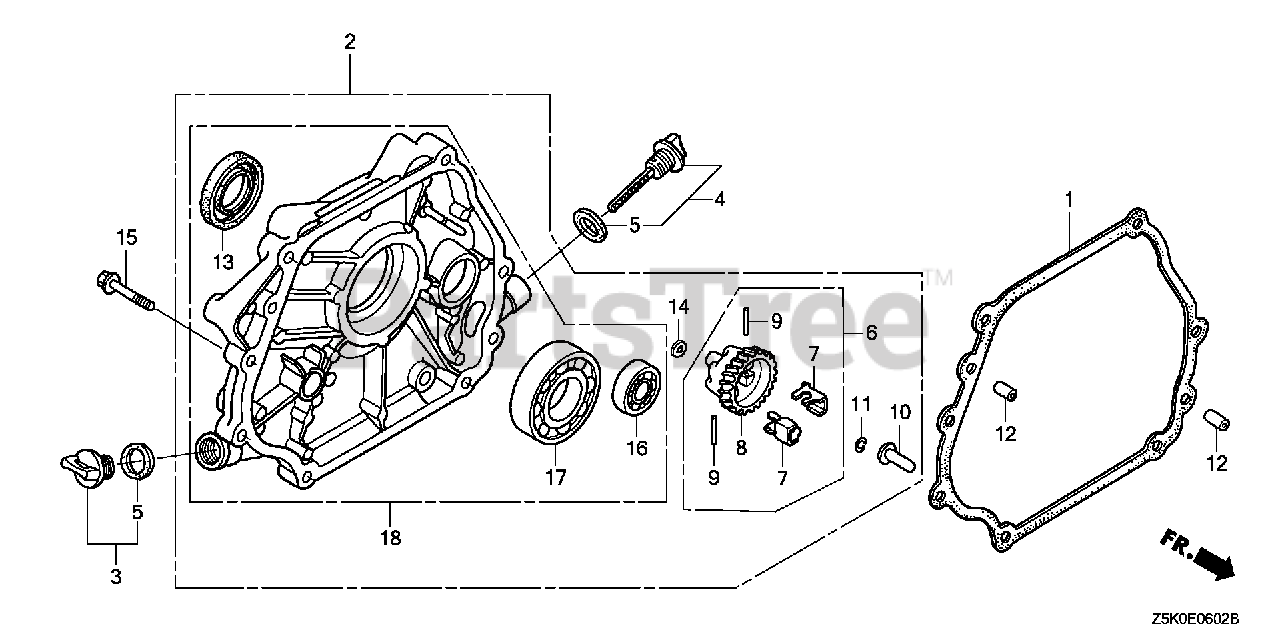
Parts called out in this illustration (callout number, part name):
1	GASKET, CASE COVER
2	COVER ASSY., CRANKCASE
3	CAP ASSY., OIL FILLER (BLACK)
4	CAP ASSY., OIL FILLER
5	GASKET, OIL FILLER CAP
6	GOVERNOR ASSY.
7	WEIGHT, GOVERNOR
8	HOLDER, GOVERNOR WEIGHT
9	PIN, GOVERNOR WEIGHT
10	SLIDER, GOVERNOR
11	CLIP, GOVERNOR HOLDER
12	PIN, DOWEL (8X12)
13	OIL SEAL (30X46X8) (NOK ASIA)
14	WASHER, PLAIN (6MM)
15	BOLT, FLANGE (8X35)
16	BEARING, RADIAL BALL (6202)
17	BEARING, RADIAL BALL (6206)
